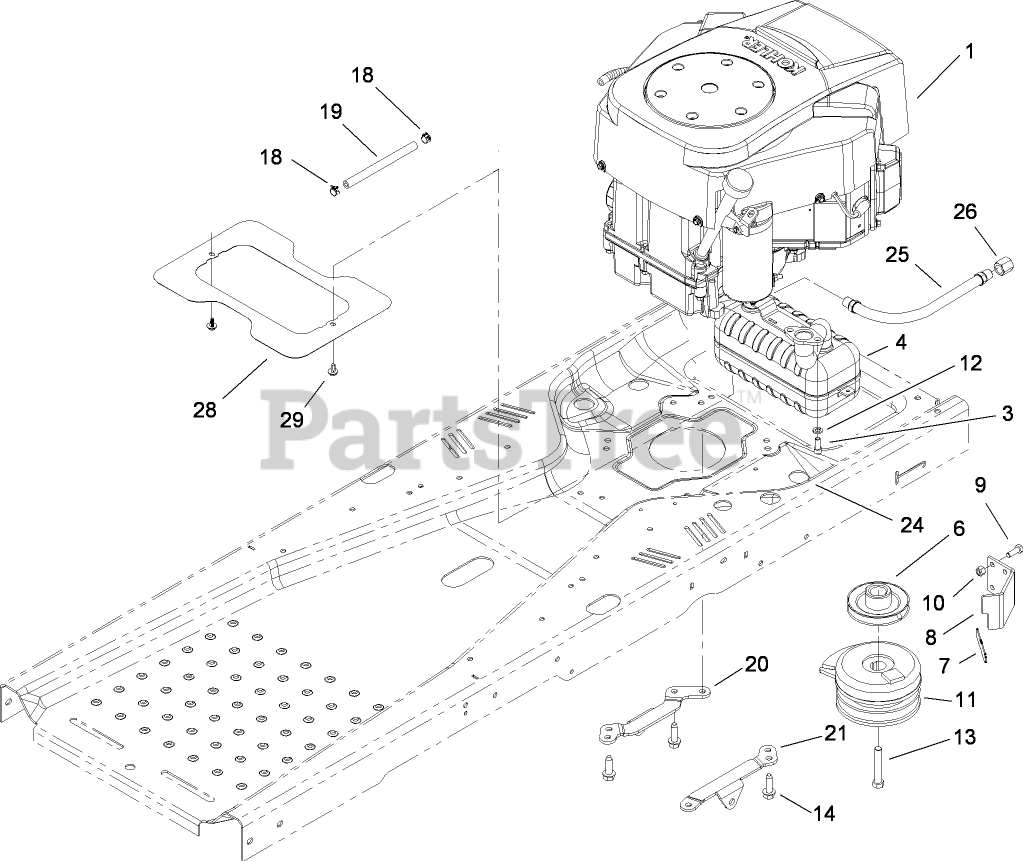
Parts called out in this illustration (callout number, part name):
1	Loose Parts Package
3	SCREW-HSH
6	PULLEY-ENGINE
7	BUMPER-PAD
8	STOP-CLUTCH
9	SCREW-HH
10	NUT-LOCK, NI
11	CLUTCH-ELECTRIC, PTO
12	WASHER-LOCK
13	SCREW-HH
14	SCREW-THD
18	CLAMP-HOSE
19	HOSE-FUEL
20	SUPPORT-HYDRO, RH
21	SUPPORT-HYDRO, LH
24	TUBING-CONVOLUTED
25	HYD HOSE ASM
26	CAP-PIPE
29	SCREW-HHFTF
